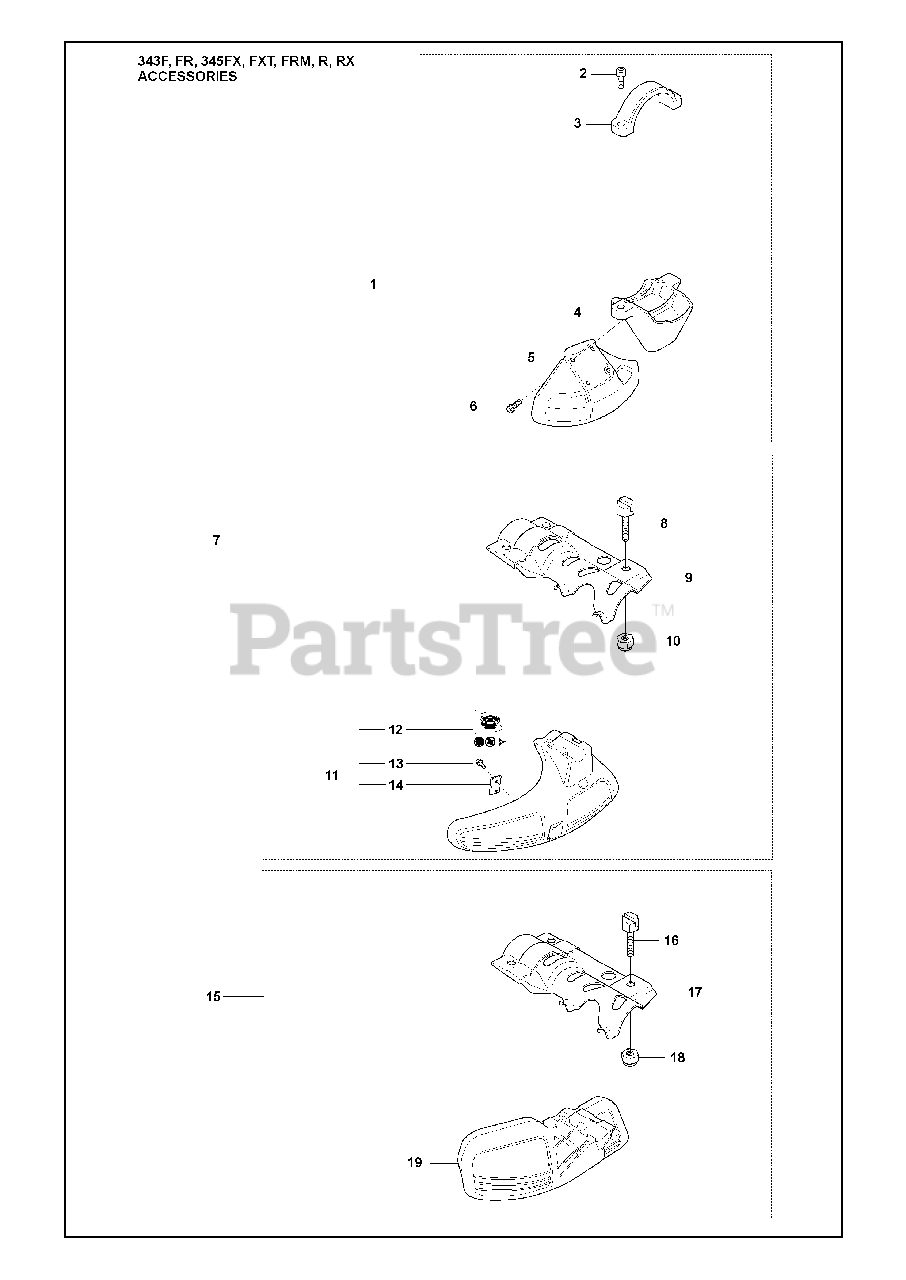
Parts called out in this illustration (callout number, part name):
1	TRIMMER GUARD ASSY
5	RP BLADE GUARD
7	TRIMMER GUARD ASSY
10	LOCKNUT M6
15	TRIMMER GUARD COMPL
18	LOCKNUT M6
19	BLADE GUARD
